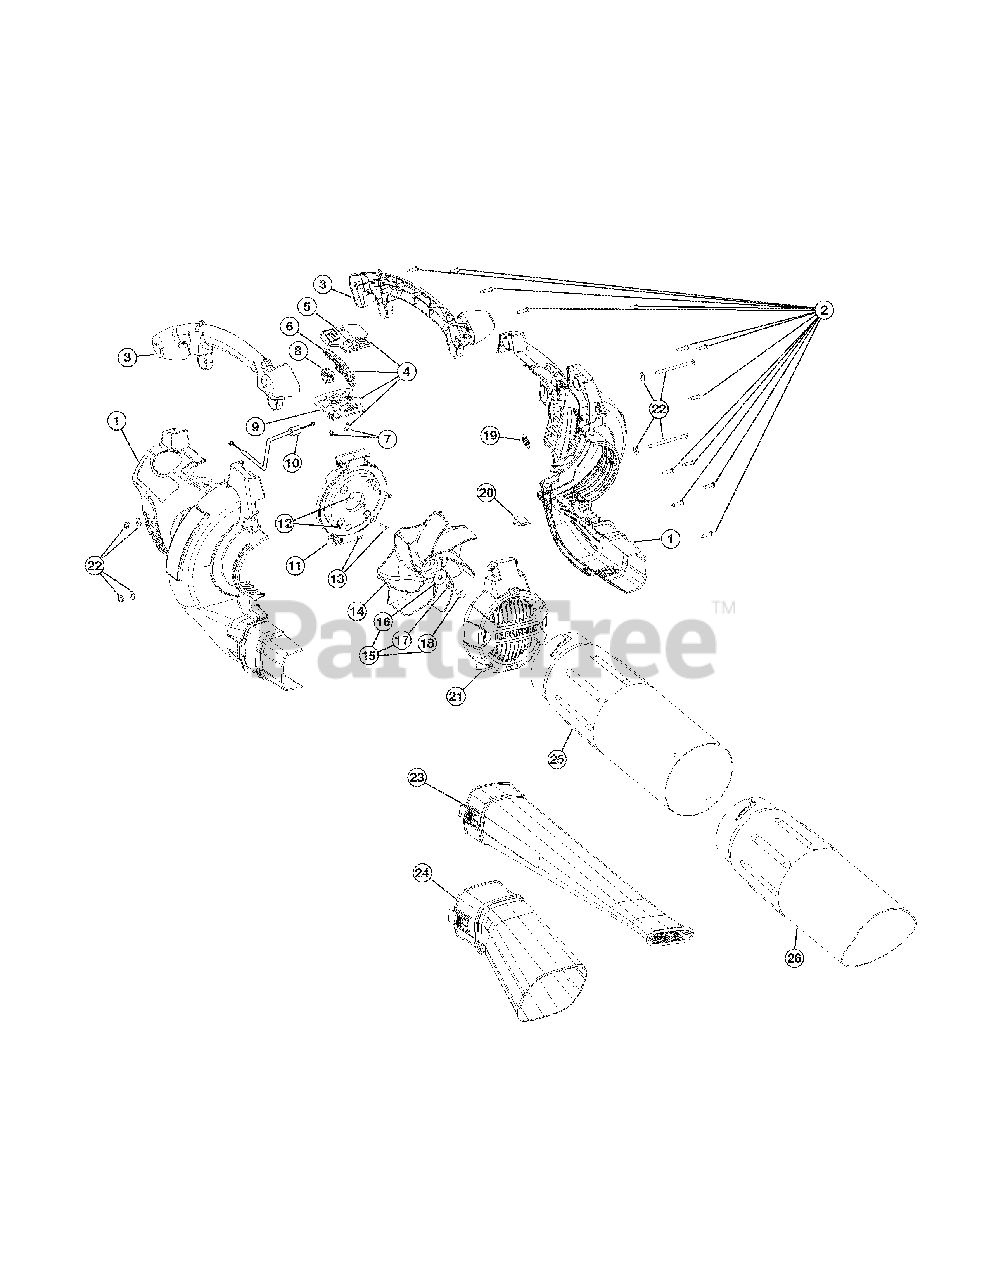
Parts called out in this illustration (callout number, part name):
1	Engine Cover Assm (includes 2)
3	Handle Assm (includes 2)
4	Throttle control Assm (includes 5-9)
5	Upper Throttle Control Plate
6	Throttle Control Lever
8	Rocker Switch Assm
9	Lower Throttle Control Plate
10	Throttle Cable
11	Engine Mount Plate (includes 12 & 13)
13	Screw
14	Impeller Blade
15	Impeller Hardware (includes 16-18)
16	Washer
17	Lock Washer
19	Vacuum Door Spring
20	Vacuum Door Lock
21	Vacuum Door
22	Mounting Plate Hardware
23	Blower Tube
24	Vacuum Bag Adaptor
25	Upper Vacuum Tube
26	Lower Vacuum Tube
